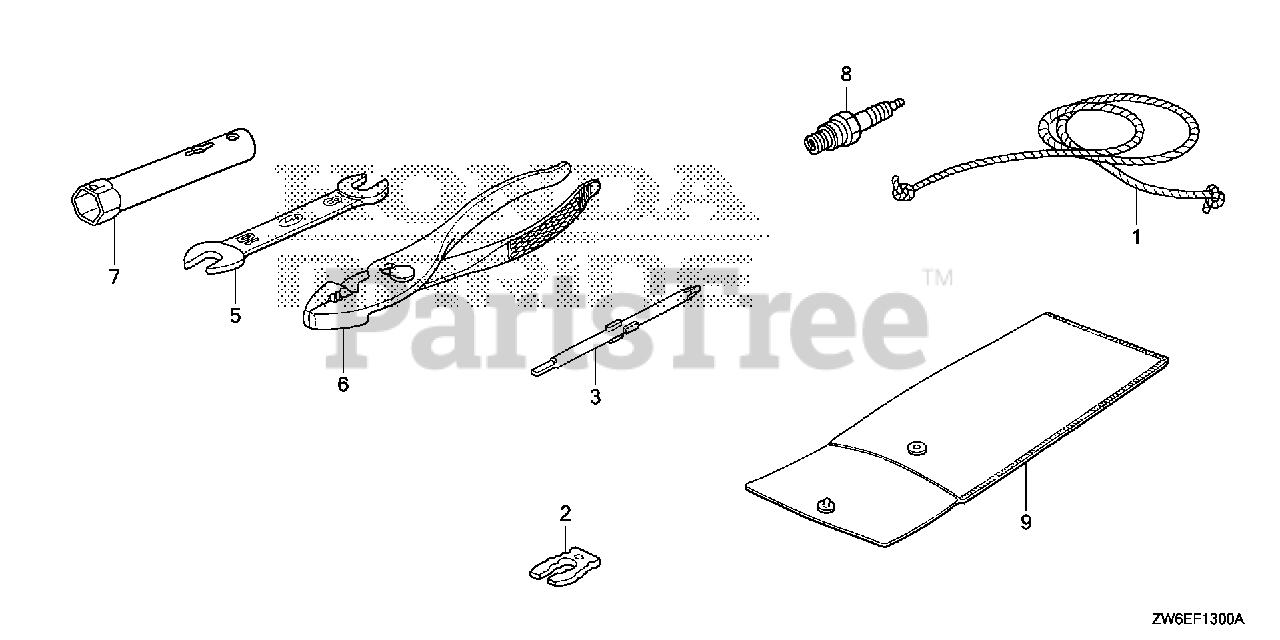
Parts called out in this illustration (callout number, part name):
1	ROPE, STARTER (N/A: USE ALTERNATE P/N 08540-ZG921-11)
2	CLIP, EMERGENCY LOCK
4	TOOL KIT (NOT AVAILABLE)
5	SPANNER (8X10)
6	PLIERS (135) (RIKEN)
7	WRENCH, SPARK PLUG
8	SPARK PLUG (1UF14-UB)
9	BAG, TOOL (160MM)
